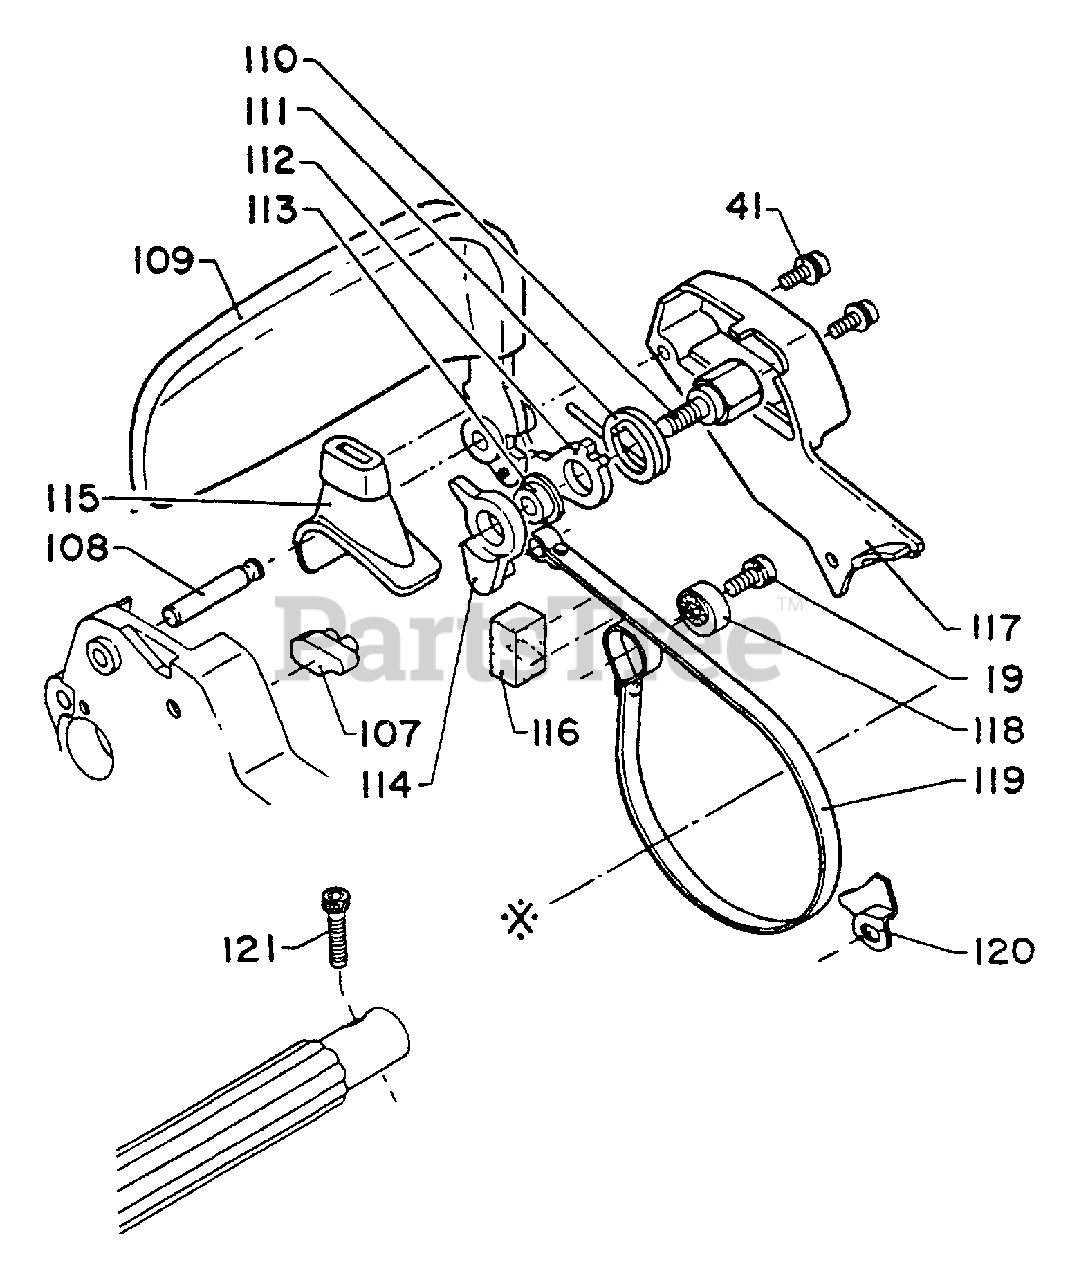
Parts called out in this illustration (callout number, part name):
19	SCREW 5×10
41	SCREW 4×10
107	RESET, BRAKE
109	HANDLE, BRAKE
111	SPRING, RETURN
114	CONNECTOR
115	COVER, BRAKE
116	SEAL
117	COVER, BRAKE
118	ADJUSTER, BRAKE BAND
119	BAND, BRAKE
120	RETAINER
121	SCREW - 5×25
